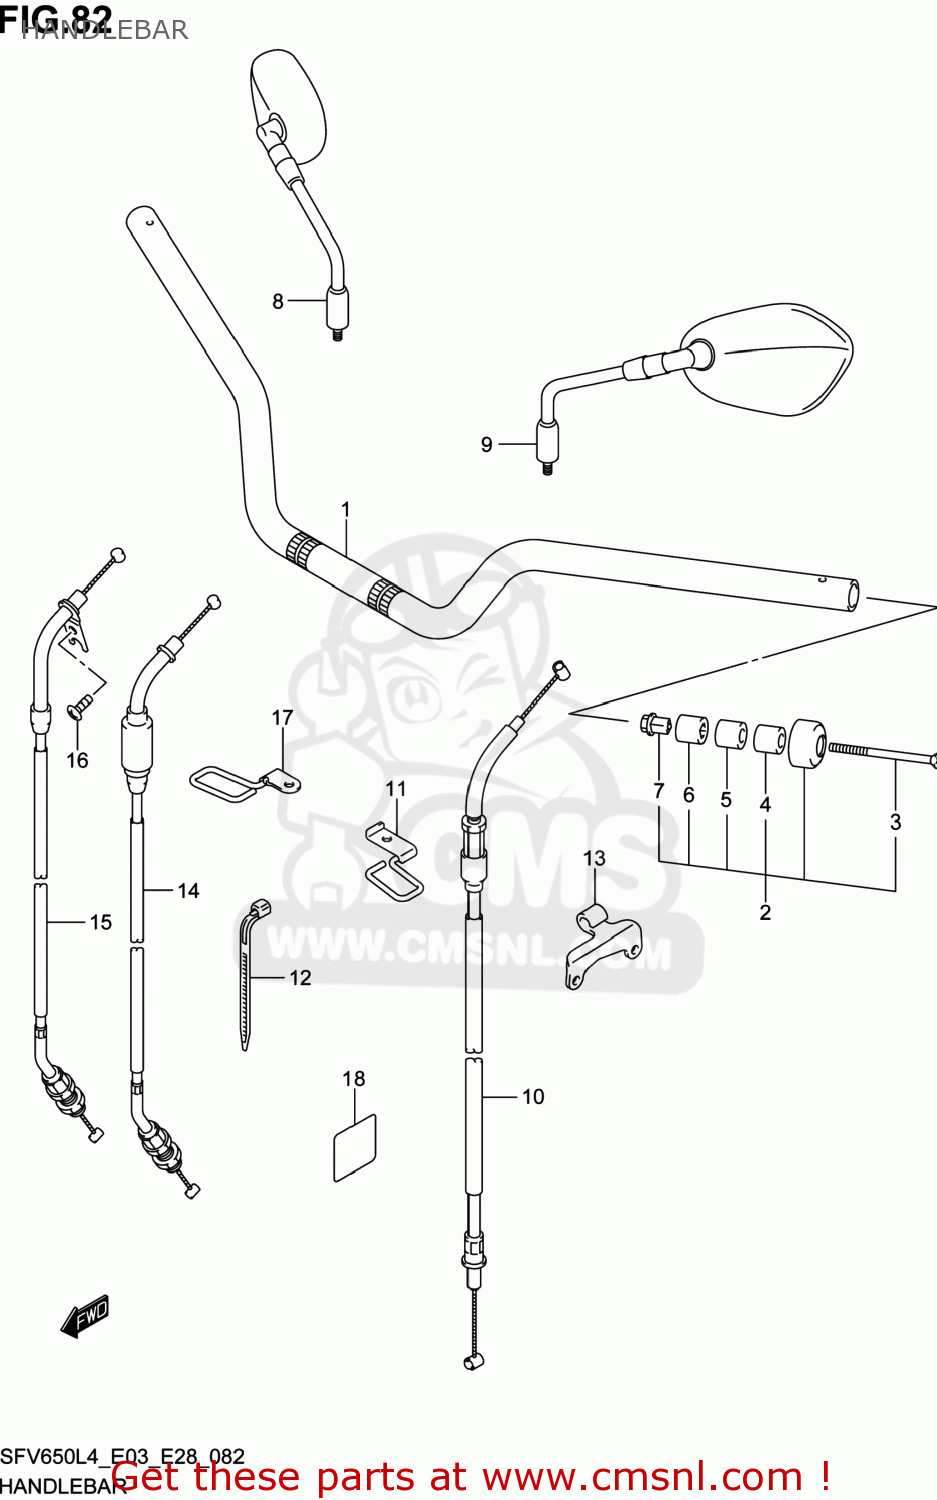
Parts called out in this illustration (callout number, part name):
1	HANDLEBAR
2	BALANCER SET,HANDLEBAR
3	SCREW
4	EXPANDER,HANDLE BALANCER
5	SPACER(6.5X16X15)
6	EXPANDER,HANDLE BALANCER
7	NUT,HANDLE BALANCER
8	MIRROR ASSY,RR VIEW,R
9	MIRROR ASSY,RR VIEW,L
10	CABLE ASSY,CLUTCH
11	GUIDE,CLUTCH CABLE
12	CLAMP(L:165)
13	STOPPER,CLUTCH CABLE
14	CABLE ASSY,THROTTLE NO.1
15	CABLE ASSY,THROTTLE NO.2
16	SCREW(5X10)
17	GUIDE,THROTTLE CABLE
18	PROTECTOR
